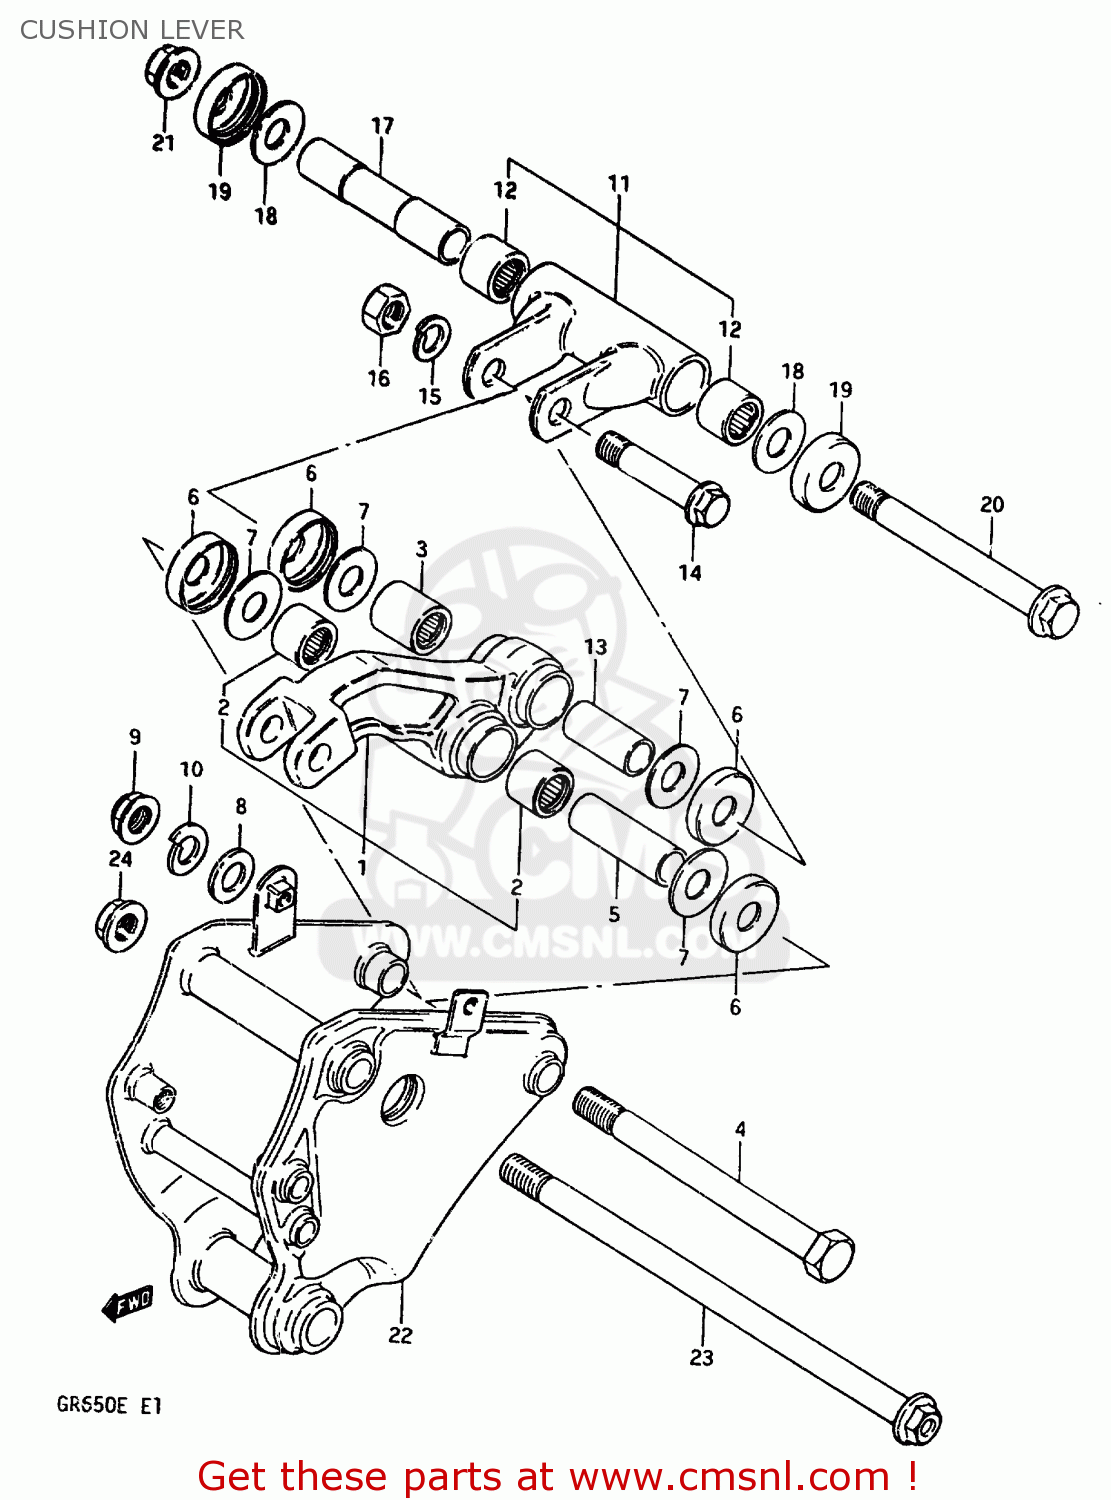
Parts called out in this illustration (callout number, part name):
1	LEVER SET,REAR CUSHION
2	ROLLER BEARING (17X24X2
3	ROLLER BEARING (17X24X25)
4	SHAFT,REAR CUSHION LEVER
5	SPACER,REAR CUSHION LEVER
6	COVER,RR SWGARM DUST SEAL
7	WASHER
8	WASHER
9	NUT 12MM
10	WASHER
11	LEVER SET,REAR CUSHION
12	ROLLER BEARING (17X24X2
13	SPACER,RR CUSHION LEVER ROD UP
14	BOLT, UPPER
15	WASHER
16	NUT
17	SPACER,RR CUSHION LVR ROD LOW
18	WASHER
19	COVER,RR SWGARM DUST SEAL
20	BOLT
21	NUT
22	BRACKET,REAR SHOCK ABSORBER
23	BOLT, BRACKET
24	NUT
